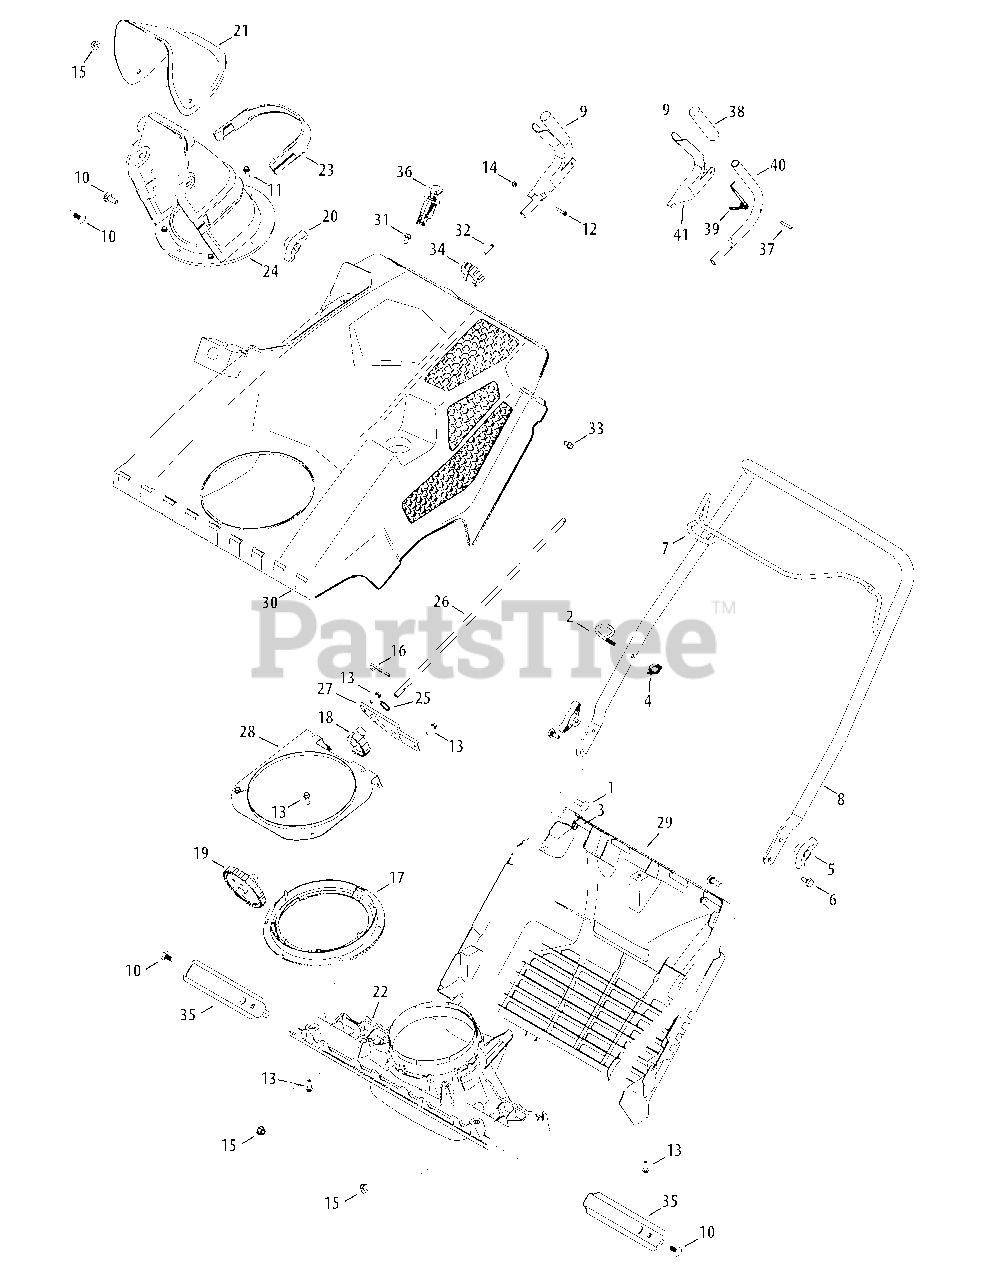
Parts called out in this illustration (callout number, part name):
1	Carriage Bolt, 5/16-18 x 1.00
2	Eye Bolt, 1/4-20
3	Flange Lock Nut, 1/4-20
4	Knob Handle
6	Shoulder Screw, .375 x .148 x 1/4-20
9	Chute Control Assembly
10	Carriage Bolt, 5/16-18 x .75
11	Hex Washer Screw, 1/4 x .750
12	Screw, #8-32 x .875
13	Screw, Hi-Lo:1/4-15, 0.75
14	Hex Lock Nut, #8-32
15	Flange Lock Nut, 5/16-18
16	Cotter Pin
17	Bevel Gear, 95T
18	Spur Gear, 35T
19	Bevel Gear, 40T/11T
20	Wing Knob, 5/16-18
21	Upper Chute
22	Chute Adapter
23	Chute Plug
24	Lower Chute
25	Flat Washer, .75 x 1.00 x .06
27	Gear Mounting Plate
28	Gear Retainer Bracket
29	Bottom Cover
30	Top Cover
31	Hex Washer Screw, 1/4-15 x .50
32	Hex Washer Screw, #8-16 x .50
33	Hex Screw, 1/4-14 x .500
34	Index Bracket
36	Ignition Switch Assembly
